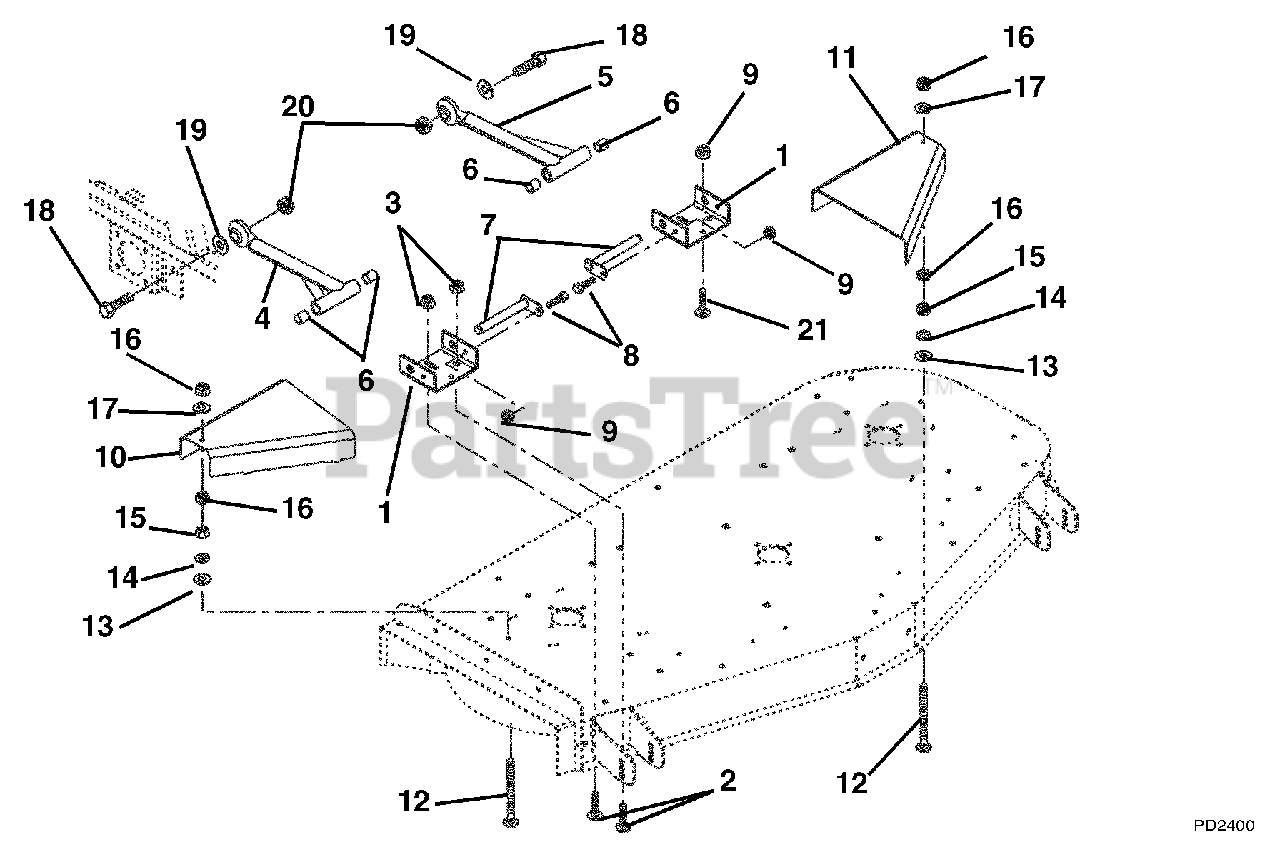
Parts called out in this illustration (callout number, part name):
1	Bracket, Mower Mounting (Rear)
2	Bolt-Round Head Square Neck .50-13 x 1.00 Grade 2
3	Nut-Locking-Center .50-13
4	Assembly, Mower Mounting Arm
5	Weldment-Mower Mounting Arm
6	Bearing .75 x .875 x 1.00
7	Weldment, Mower Mounting Pin
8	Bolt-Hex .38-16 x .75 Grade 5
9	Nut-Locking-Center .38-16
10	Guard, Pulley Right Hand (036, 038, 309)
10	Guard, Pulley Right Hand (037, 039)
11	Guard, Pulley Left Hand (036, 038, 309)
11	Guard, Pulley Left Hand (037, 039)
12	Bolt-Round Head Square Neck .31-18 x 3.50
13	Washer-Flat-Steel .344 x .688 x .065
14	Washer-Locking .31 x .078
15	Nut-Hex .31-18
16	Nut-Locking-Center .31-18
17	Washer-Flat-Steel .438 x 1.00 x.083
18	Bolt-Hex .875-9 x 2.75 Grade 5
19	Washer-Flat-Steel .875 x 1.50 x .120
20	Nut-Locking-Center .875-9
21	Bolt-Round Head Square Neck .38-16 x 1.00 Grade 5
